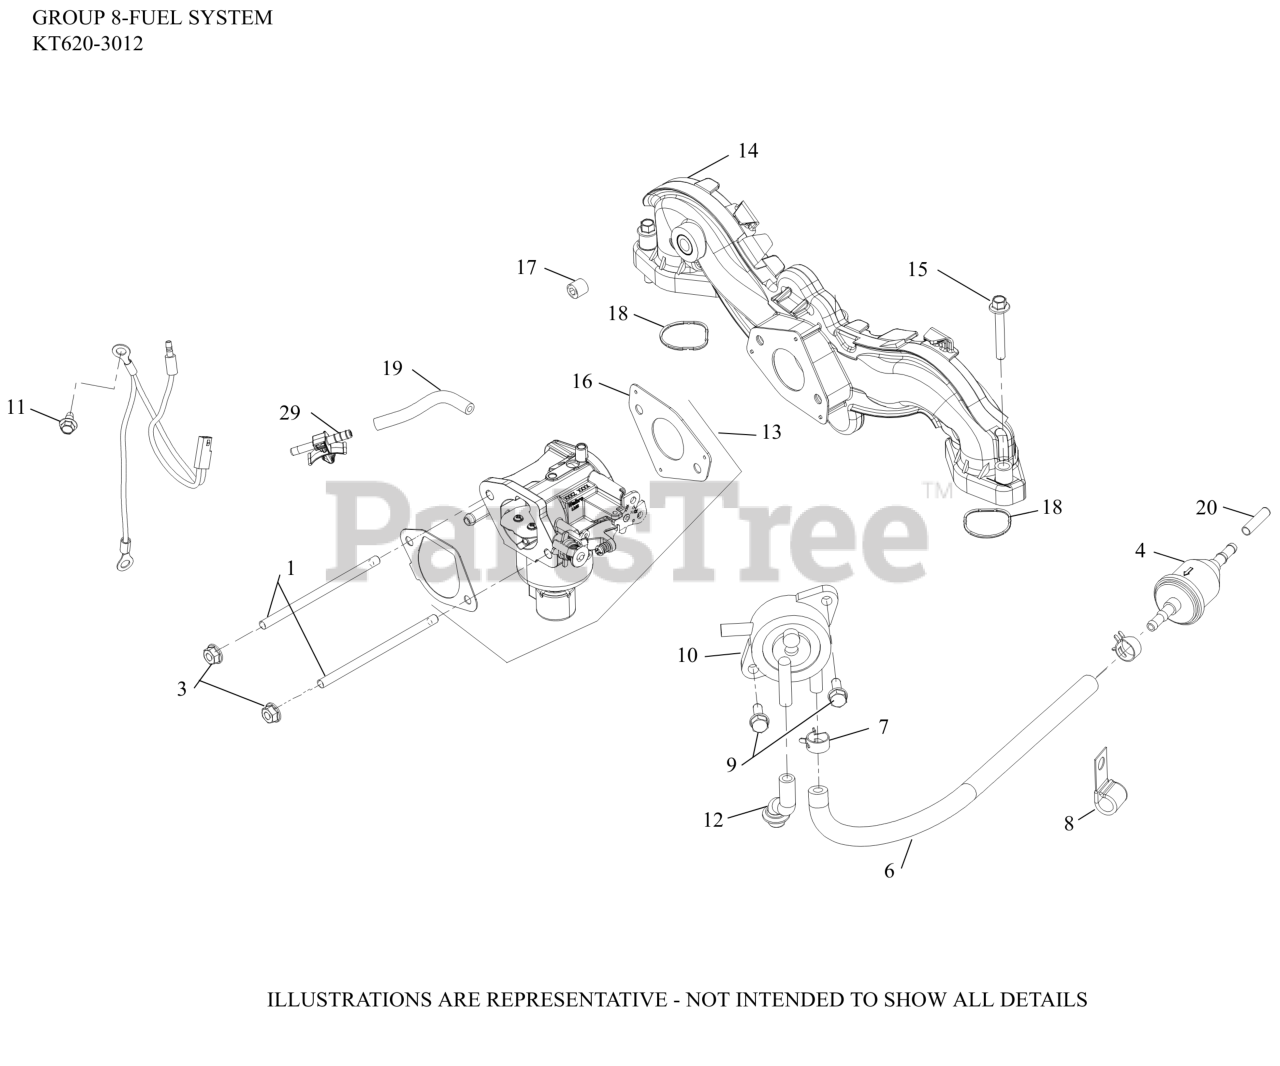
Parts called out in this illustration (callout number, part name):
3	NUT, FLG M6X1.0
4	FILTER,FUEL 51 MICRON (FUEL PUMP)
6	HOSE,LW PERM.FUEL 24.00"-USE 25 111 81-S
7	SPRING CLAMP, HOSE
8	CLIP, CABLE
9	SCREW, TAP M6X1.7X18
10	PUMP, FUEL (PULSE)-(#2539326S)
11	SCREW, THREAD FORMING
12	HOSE, PULSE PUMP(STEEL COVERS)
13	KIT,CARB(WALBRO)
14	KIT, INTAKE MANIFOLD-(#24164277S)
15	SCREW, FLG M6X1.0X40
16	GASKET, CARBURETOR
17	PLUG, CTSK PIPE 1/8"
18	O-RING, INTAKE PORT (PIM)
19	HOSE EVAPORATIVE (WALBRO)
20	CAP, MASKING
29	CONNECTOR, EVAPORATIVE
NI	KIT,REPAIR OVERHAUL(WALBRO)
NI	KIT,BOWL O-RING(WALBRO)
NI	KIT, HI ALTITUDE (5000 FT) 19MM
NI	KIT,SOLENOID REPAIR(WALBRO)
NI	KIT,REPAIR FLOAT(WALBRO)
